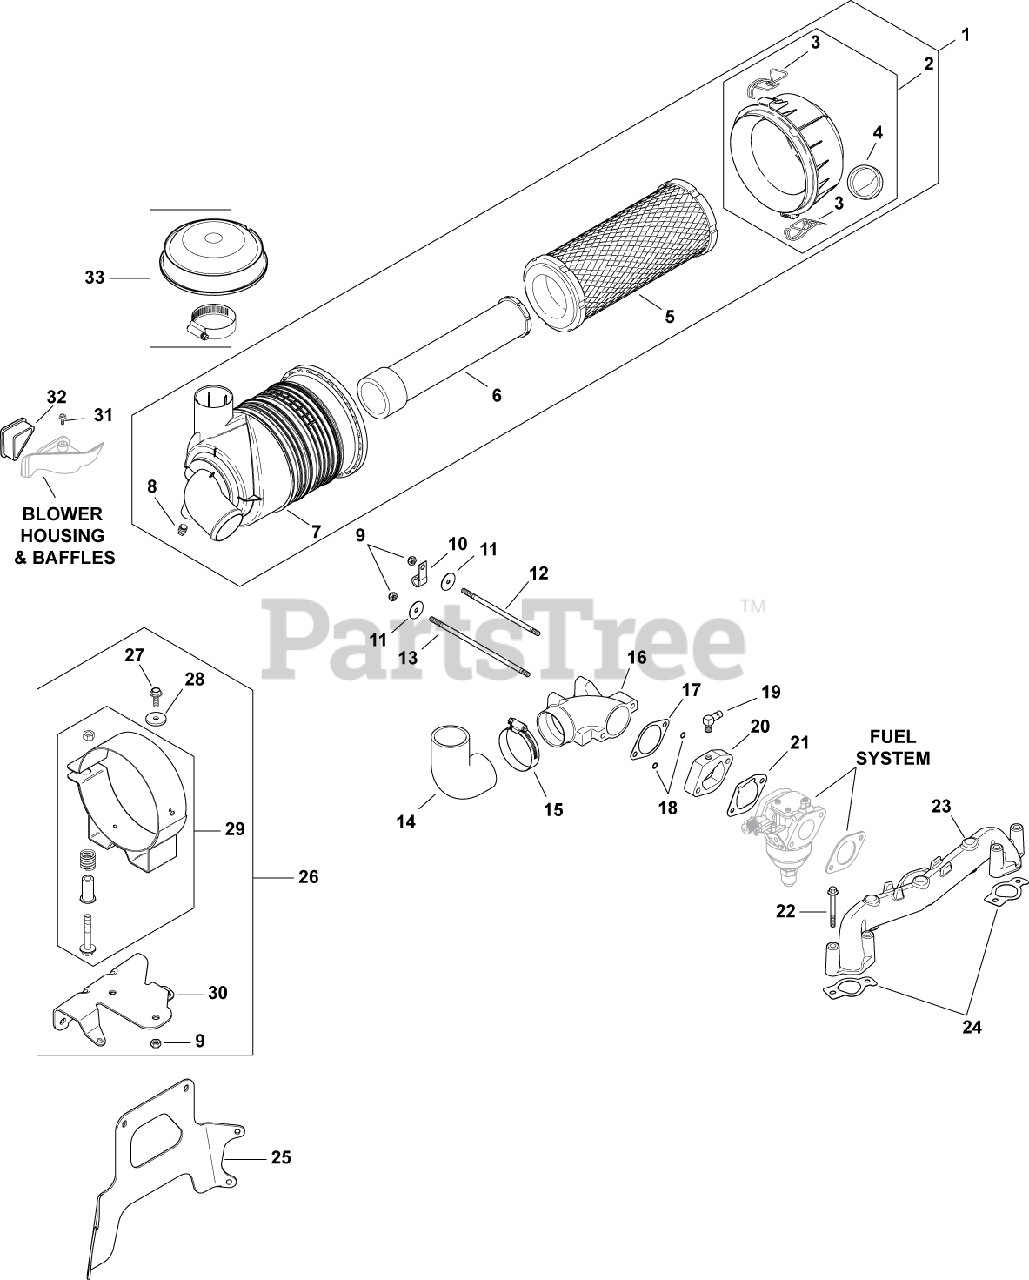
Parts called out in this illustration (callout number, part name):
1	AIR CLNR, CANISTER-USE 25 048 17-S
2	COVER ASSEMBLY, AIR CLEANER
3	CLIP - USE 62 154 07-S
4	VALVE, DUST EJECTOR
5	ELEMENT, AIR FILTER - PRIMARY
6	ELEMENT, AIR FILTER - SAFETY
7	HOUSING, HD AIR CLEANER
8	PLUG, PIPE
9	NUT, LOCK M6X1.0
10	CLIP, CABLE
12	STUD, M6X1.0X140
13	STUD, M6X1.0X180
14	HOSE, AIR CLEANER
15	CLAMP, HOSE
16	ADAPTER, ELBOW
17	GASKET, AIR CLEANER ADAPTER
19	CONNECTOR, HOSE
20	ADAPTER, BREATHER FITTING
21	GASKET, AIR CLEANER BASE
22	SCREW, FLG M6X1.0X55
23	MANIFOLD, INTAKE
24	GASKET, INTAKE MANIFOLD USE 24 041 79-S
25	BRACKET, MAIN SUPPORT-USE 24 126 185-S
26	BRACKET, AIR CLEANER -USE 24 126 186-S
27	SCREW, FLG M6X1.0X16
28	WASHER, FLAT 1/4" (O.D. 1")
29	BRACKET, AIR CLEANER-USE 24 126 191-S
30	BRACKET, AIR CLEANER-USE 24 126 184-S
31	SCREW, WSH HD TAP #8-18X1/2"
32	COVER, BLOWER HOUSING USE 24 096 160-S
33	HOOD, AIR CLEANER (5.25)-USE 25 324 04-S
